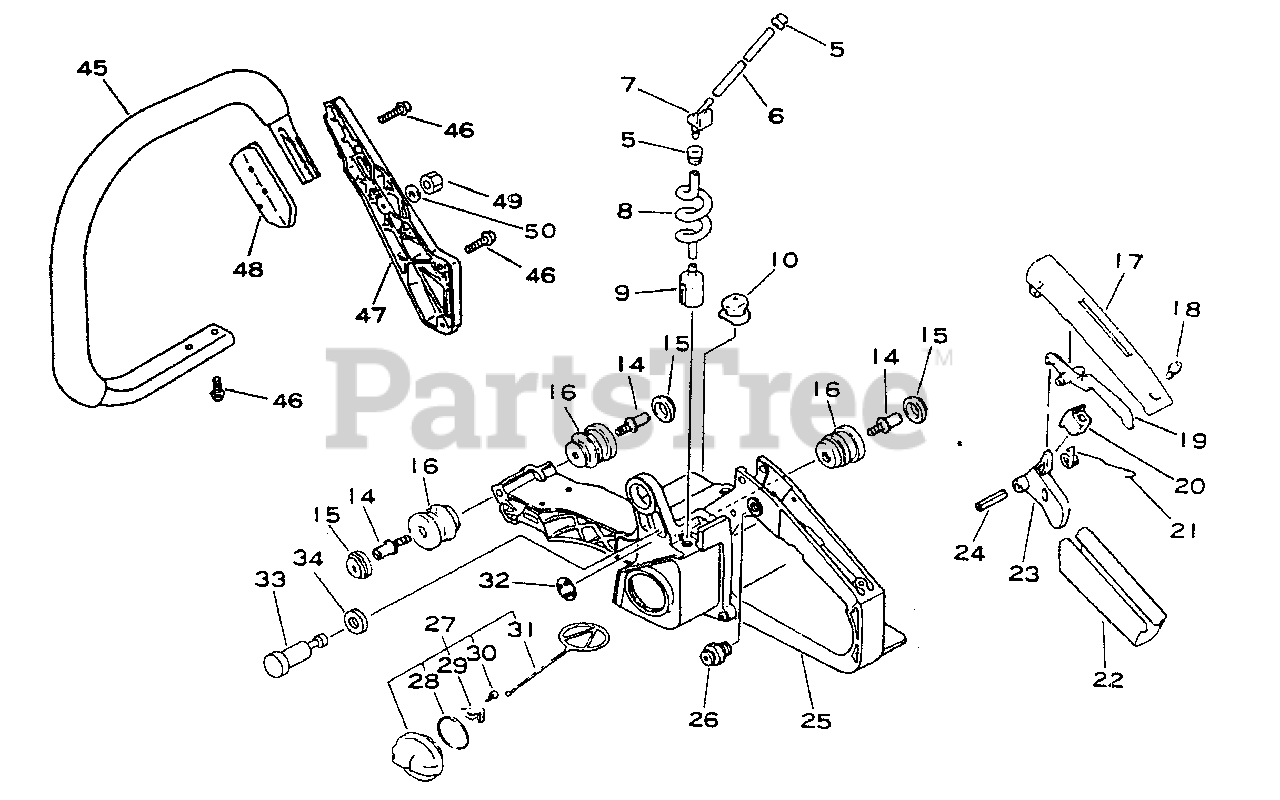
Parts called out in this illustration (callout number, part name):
5	GROMMET
6	PIPE, FUEL - 3×6×100
7	CONNECTOR, PIPE
8	PIPE - SPIRAL
9	FILTER, FUEL
15	CAP, CUSHION
16	CUSHION
17	COVER, HANDLE
18	SCREW 4×14
19	CONTROL, THROTTLE
20	CUSHION, THROTTLE
21	SPRING, THROTTLE RETURN
23	TRIGGER, THROTTLE
24	PIN, SPRING Ø5×25 MM
25	HANDLE, REAR
26	LOCK, THROTTLE
27	CAP ASSY
28	O-RING 29
29	RETAINER, CONNECTOR
30	SCREW 3×8
31	CONNECTOR, CAP L= 60 MM
32	CUSHION (B)
33	VENT ASSY
34	GROMMET, FUEL
45	HANDLE, FRONT
46	SCREW 5×20
47	SUPPORT, HANDLE
48	BRACKET, HANDLE - INNER
49	NUT, SLOT 5
50	WASHER, FLAT 5.5×10×0.8
